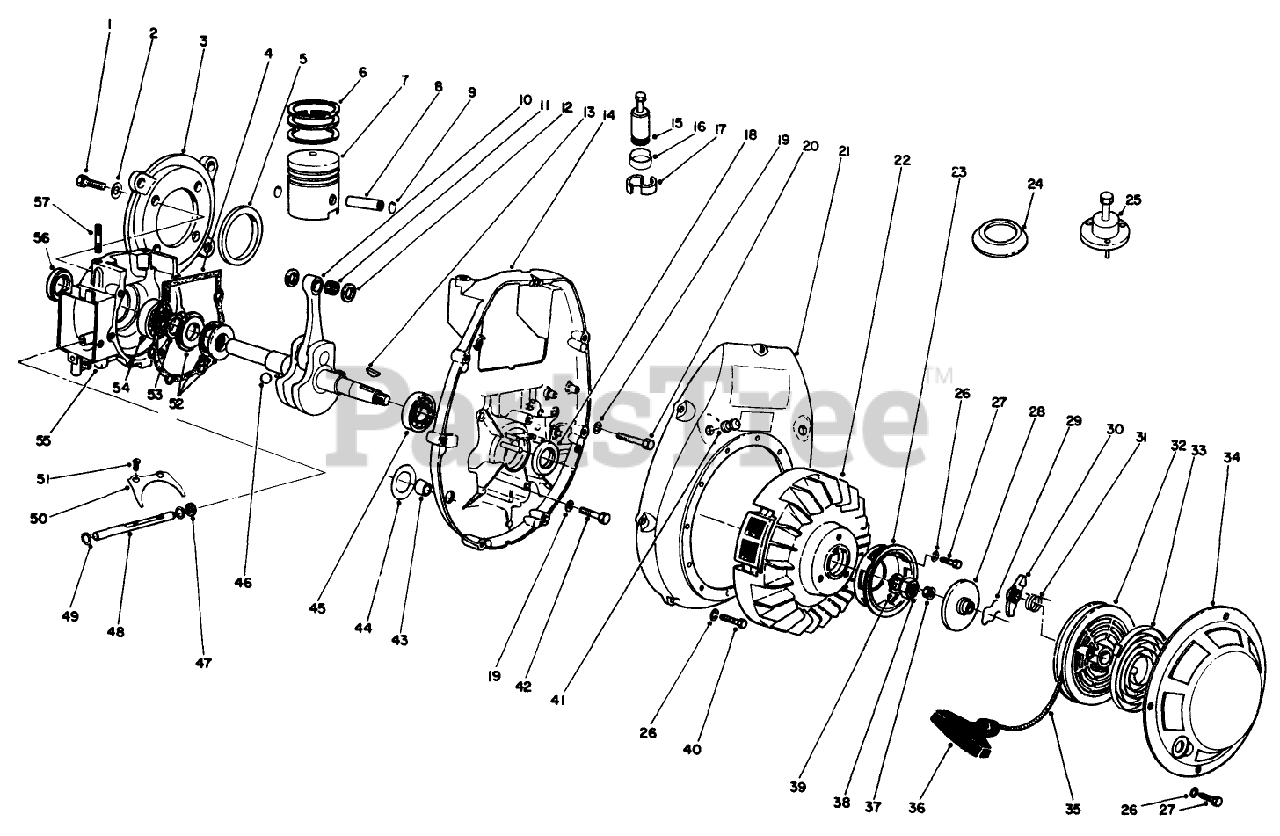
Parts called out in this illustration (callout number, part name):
1	Capscrew
2	Lockwasher
3	Intermediate Flange Ring
4	CRANKCASE GASKET
6	Piston Rings
7	Piston-Std. 69 MM Dia. (Incl. Ref. #6, 8 & 9)
8	Wrist Pin
9	Locking Ring
10	Crankshaft Assembly
11	Bearing-Needle
12	Washer
13	Key-Woodruff
14	Crankcase
15	Extractor
16	Retaining Ring
17	Half Bushes (Pair)
18	Oil Seal
19	Lockwasher
20	Capscrew-Hex Hd.
21	Cover-Fan
22	Wheel-Fan
23	Carrier
24	Meter-Revolution Frequency
25	Puller
26	Lockwasher
27	Screw-Hex Head
28	Brake-Disc
29	SPRING
31	Spring
32	Pulley-Rope
33	PISTON/PIN ASM
34	Housing-Starter
35	Rope (Incl. Ref. #36)
36	Handle
37	CAP-END
39	Washer
40	HEX HEAD SCREW
42	Screw-Hex Head
44	Washer
45	Ball Bearing
47	Seal-Oil
48	Shaft-Governor
49	Washer
50	Fork-Governor
51	Screw
52	Needle Bearing Assembly
53	Washer
54	Ball Bearing
55	Crankcase-PTO Side
56	Oil Seal
